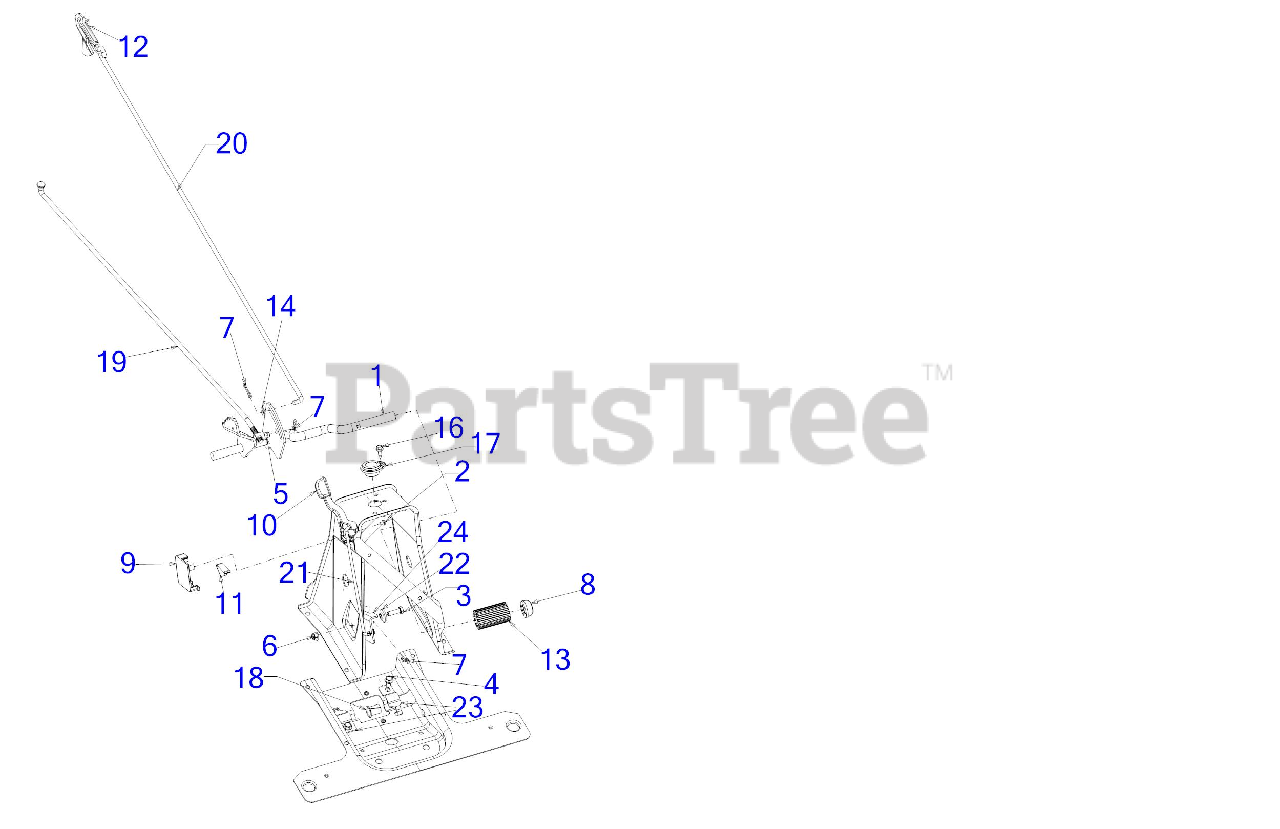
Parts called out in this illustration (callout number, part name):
2	HEX SCREW AB-TAP #10-16 x 0.500
3	SCREW 5/16-18 x 1.0 GR5
4	SCREW 5/16-18 x .750
5	FERRULE 3/8-24 x .375
6	FLANGE LOCK NUT 5/16-18
7	BOW TIE COTTER PIN 1/4-5/16
9	6 SPEED CONTROL COVER
10	6 SPEED LEVER
11	SHIFT SPRING
12	EXTENSION SPRING .59 OD x 4.0
13	FOOT PAD 2.5"
14	FLAT WASHER
16	SHOULDER SCREW
17	FLANGE BEARING
18	FLANGE BEARING .626 x .938 x .875
19	VARIABLE SPEED ROD
21	SPEED SELECT ROD
22	SHOULDER SPACER
23	BRAKE SHAFT STRAP
